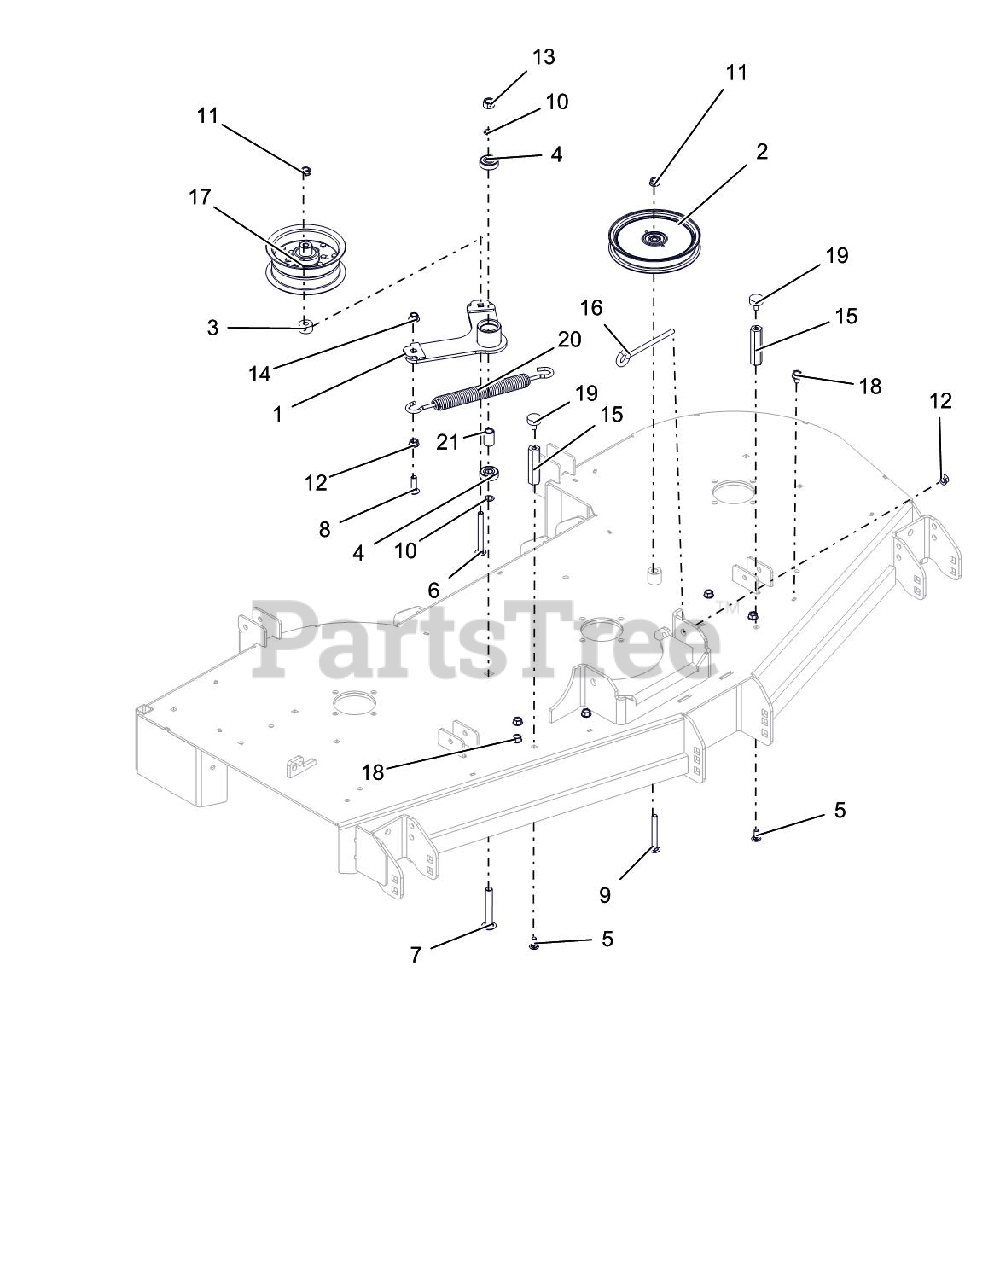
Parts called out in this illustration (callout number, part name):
1	WLDMT, DECK IDLER ARM
2	IDLER, FLAT-6.00" X .75"
3	SPACER .390X1.000X.562
4	BRG-BALL .500X1.38X.437
5	BLT,RDHDSQNK .31-18X.75 LOCTIT
6	BLT-RHDSSQNK .38-16X3.50 G5YZ
7	BLT,RDHDSQSHNK.50-13X3.25 G5YZ
8	BLT-RHDSSQNK .38-16X1.25 G5YZ
9	BLT-RDHDSQNK .38-16X3.00 G5YZ
10	WASHER, .500X.750X.020 THRUST
11	NUT-LK-CTR-FLG .38-16 YWZC
12	NUT-SPNLK-FLG .375-16 YWZC
13	NUT-LK-CTR .50-13 YWZC
14	NUT-LK-NYL-FLG .38-16 YWZC
15	NUT, COUPLING .31-18 X 3.00
16	BOLT,.38-16 X 4.25-.62 DIA EYE
17	PULLEY, FLAT 5.00X2.36X.375
18	SCR-TAP .38-16X.50 HWH TR YWZ
19	BUMPER, RUBBER
20	SPRING, EXTENSION
21	SPACER .510 X .75 X 1.1485
